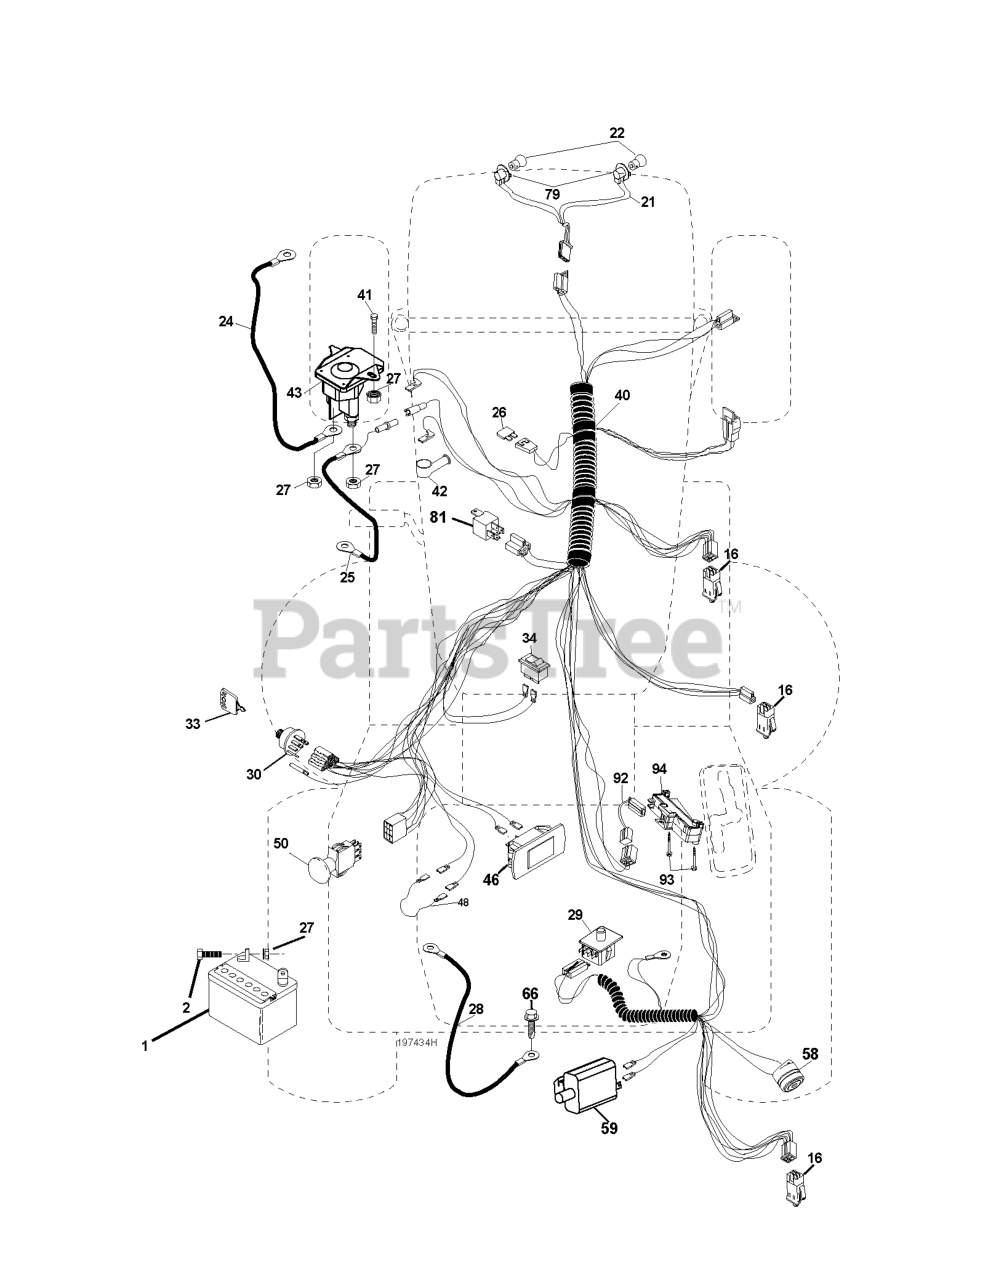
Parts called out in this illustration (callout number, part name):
1	BATTERY 12V .35 AMP
2	BOLT.HEX.1/4.X.3/4.DICHROMATE
16	SWITCH INTERLOOK PUSH-IN
21	HARNESS.LIGHT W/4152J BULBS
24	BATTERY CABLE GT
25	CABLE BATTERY
26	FUSE 20AMP
27	NUT
28	CABLE GROUND
29	SWITCH.SEAT.DP W/RAMPS
30	SWITCH.IGN.DELTA.W.LGH.ROS
33	KEY MLD GEN DELTA
40	RP HARNESS.IGN.ELECT.REG.CRD
41	BOLT
42	TERMINAL COVER
43	SOLENOID.W/BRASS.PLUNGER
46	RP.GUAGE.SRVCMNDR.HRMTR.
48	ADAPTER.AMMETER
50	RP.PTO.SWITCH.8 TERMINAL.BLACK
58	BUZZER
59	.WITCH.FULL BAGGER.INDICATOR
79	BULB HOLDER ASM.
81	RELAY.ASSY.T
92	HARNESS.PIGTAIL.CONSLE
93	SCREW.PLASTITE
94	MODULE.REVERSE.ROS
